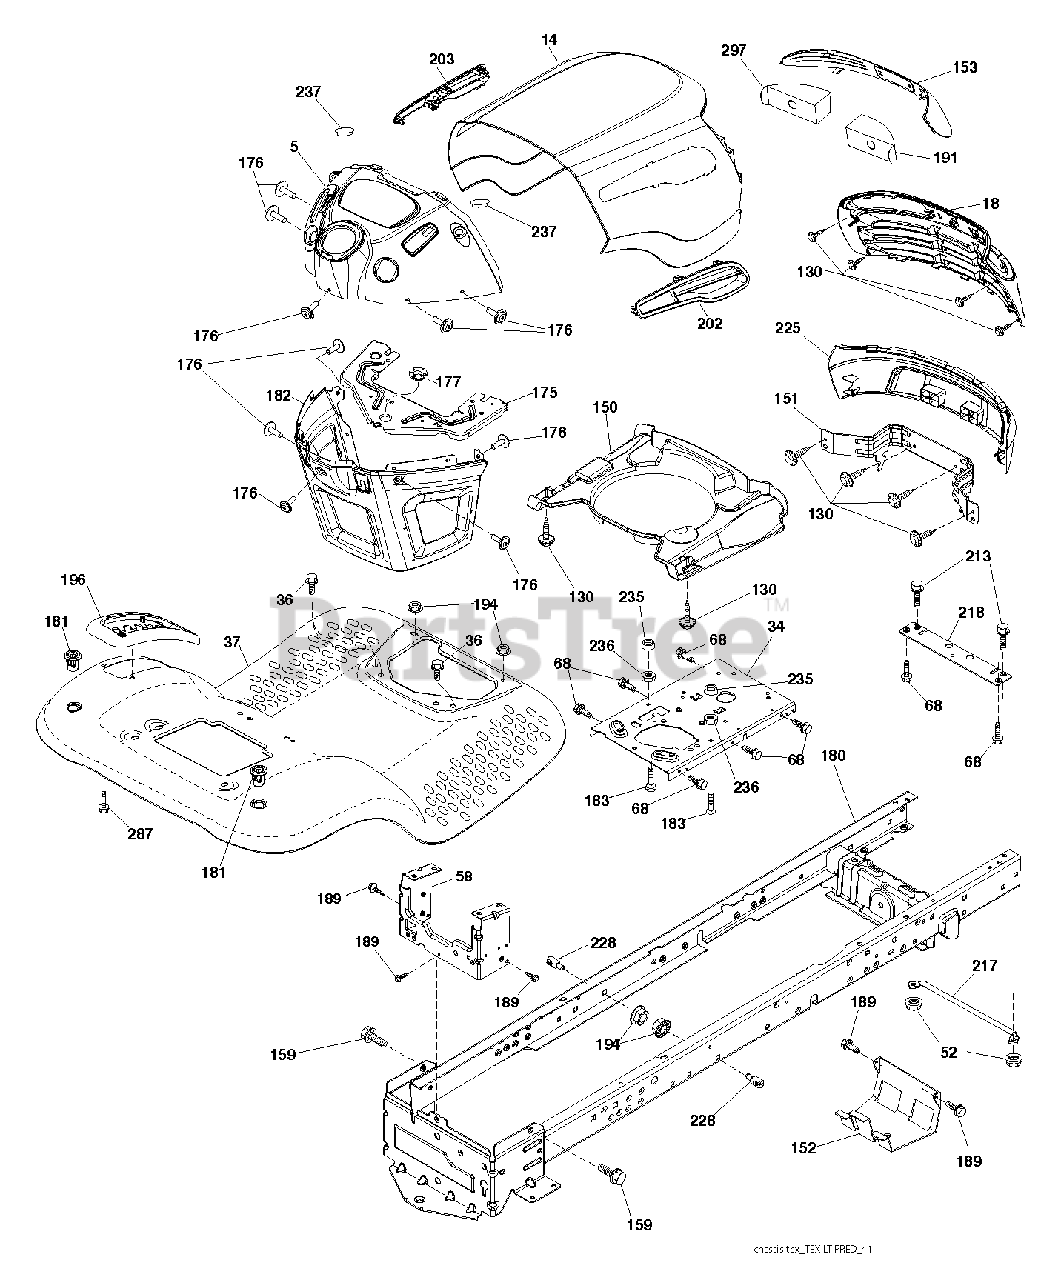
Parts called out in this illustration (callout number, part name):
5	DASH.PREDLT.CC.ICY.CK.N/SRV.BL
14	HOOD.PNT.PREDATOR.LT.TX.667
18	GRILLE.SVC.BASE.PREDATOR.LT428
34	Engine Welded Chassis Plate
36	SCREW 5/16"
37	FENDER.TLT.FS.W/NO CUPHLD.667
52	LOCKNUT
58	DRAWBAR UPPER 2PC SMALL FENDER
130	SCREW.#10 X 0.750.BOS THREAD
150	DUCT.AIR.PREDATOR.LT.2.36"
151	BRACKET.PIVOT.ALPHA.LT
152	SHIELD BROWNING
153	LENS.PREDATOR.LT
159	SCREW, 3/8-16X3/4
176	SCREW.#10-24X5/8.RN.QU
177	BUSHING STEERING
180	CHASS.WLDMNT.TL.12GA/2P.48/54
181	FEND/FTRST.PCH.CPH.NFW
182	DASH.LWER.PREDATOR/HUSQ.LT
183	BOLT.5/16-18X1-1/4 FULL THD
189	SCREW
191	INSERT.REFLECT.PREDATOR.LT.RH
194	NUT LOCK HEX FLANGE 5/16-18
196	CONSOLE.ASM.DECKLFT.BL/RBT.TLT
203	VENT.SIDE.PRED.LT.LH.JONSERED
213	BOLT
217	ROD.PIVOT.HOOD
218	X-PIECE.HOOD.STOP.NON/
225	BUMPER.GRILLE.PRED.LT.JONS.505
228	STUD.FASTNER.W/ANTI-ROTATE
235	SPACER FENDER
236	NUT.CENTERLOCK.5/16-
237	PLUG.MOUNT.CARGO.BLK
297	REFLECTOR.INSERT.PRED.LH.LT
